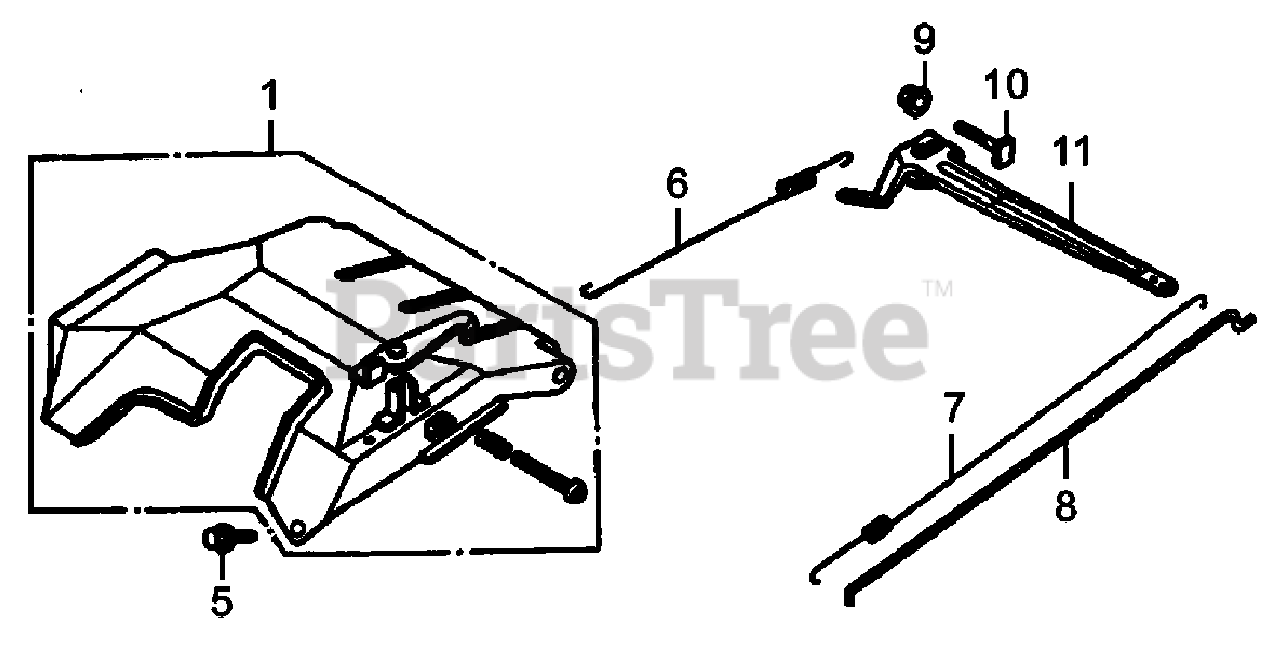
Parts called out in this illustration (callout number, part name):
1	CONTROL ASSY.
5	BOLT, FLANGE, 6 X 12
6	SPRING, GOVERNOR A
7	SPRING, GOVERNOR B
8	ROD, GOVERNOR
9	NUT, FLANGE, 6MM
10	BOLT, GOVERNOR ARM
11	ARM, GOVERNOR
